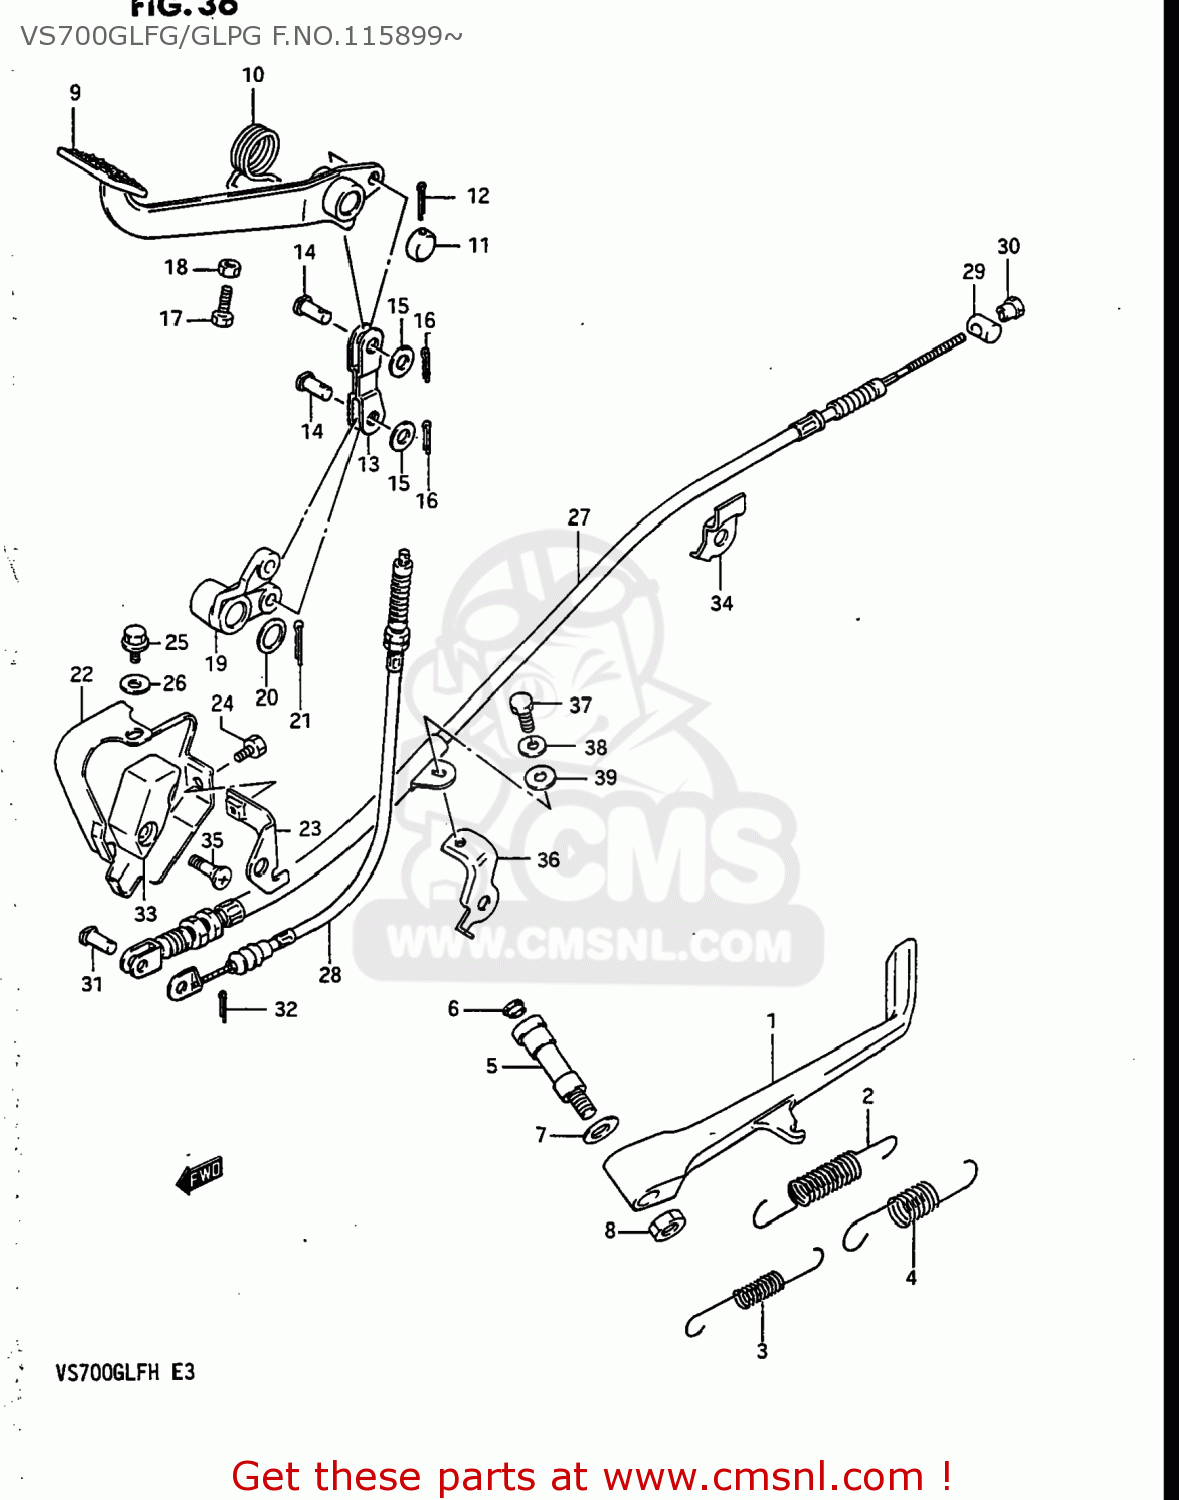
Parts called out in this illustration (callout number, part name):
1	SWING ARM,REAR
2	BEARING(22X29X20)
3	SPACER,REAR SWING ARM PIVOT
4	SPACER,RR SWGARM PIVOT
5	CVR,RR SWGARM DUST SEAL(OD:40)
6	WASHER
7	SHAFT,RR SWINGINGARM PIVOT
8	NUT
9	CAP,REAR SWING ARM PIVOT
10	COVER,REAR SWING ARM PIVOT
11	BOOT,PROPELLER SHAFT
12	CLAMP
13	SCREW 4X25
14	TORQUE LINK,REAR
15	BOLT(10X28)
16	WASHER
17	NUT
18	SPACER
19	BOLT(10X41)
20	WASHER (10X20X2.3)
21	NUT
22	COTTER PIN
23	CAP
24	CUSHION
25	ABSORBER ASSEMBLY,REAR SHOCK
26	WASHER
27	NUT, LOWER LH
28	BOLT(10X39)
29	SPACER (10.2X14X20.7)
30	WASHER
31	NUT, LOWER LH
32	WASHER 10MM
